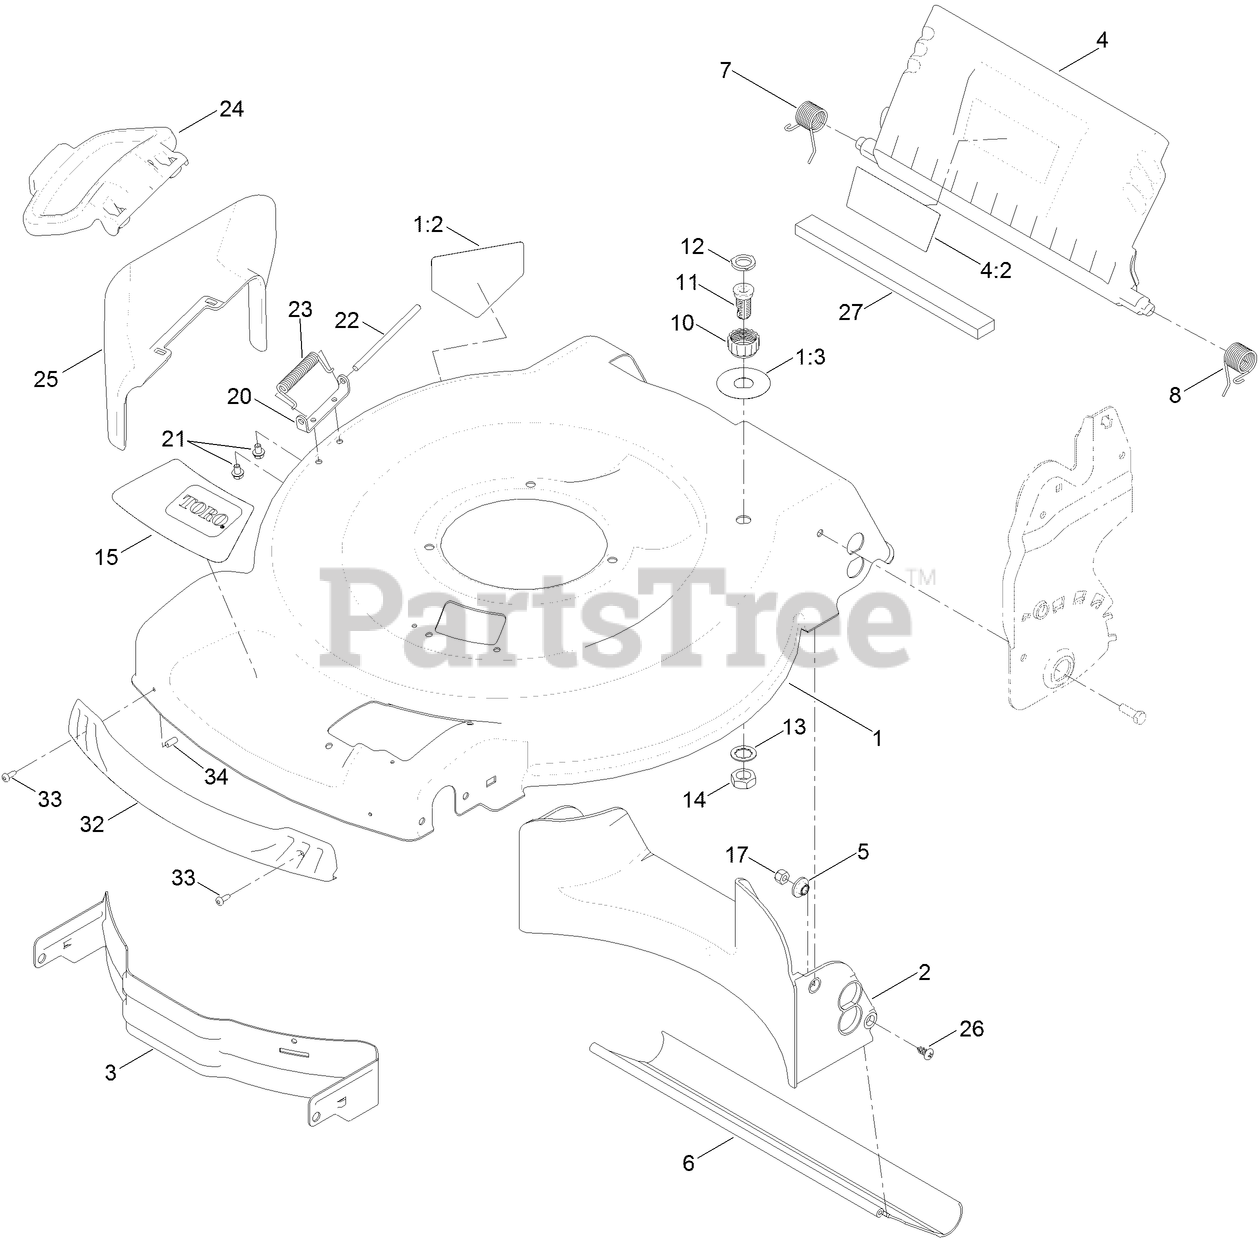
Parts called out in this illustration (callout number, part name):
1	HOUSING ASM
1:2	DECAL-DANGER
1:3	DECAL-PORT, WASHOUT
2	BAFFLE-REAR
3	BAFFLE-FRONT
4	REAR DEFLECTOR ASM
4:2	DECAL-WARNING
5	WASHER-STEPPED, BAFFLE
6	SHIELD-TRAILING
7	SPRING-TORSION
8	SPRING-TORSION
10	COUPLING-HOSE, WASHOUT PORT
11	PORT-WASHOUT
12	WASHER-SEAL, WASHOUT PORT
13	WASHER-LOCK
14	NUT-JAM
15	DECAL-DECK
17	NUT-LOCK, NI
20	BRACKET-COVER
21	SCREW-HWH
23	SPRING-TORSION
24	DEFLECTOR-SIDE
25	CHUTE-DISCHARGE, SIDE
26	SCREW-PTH
27	FOAM-SEAL
32	BUMPER
33	SCREW-FORMING, THREAD
34	CAP-PLUG
